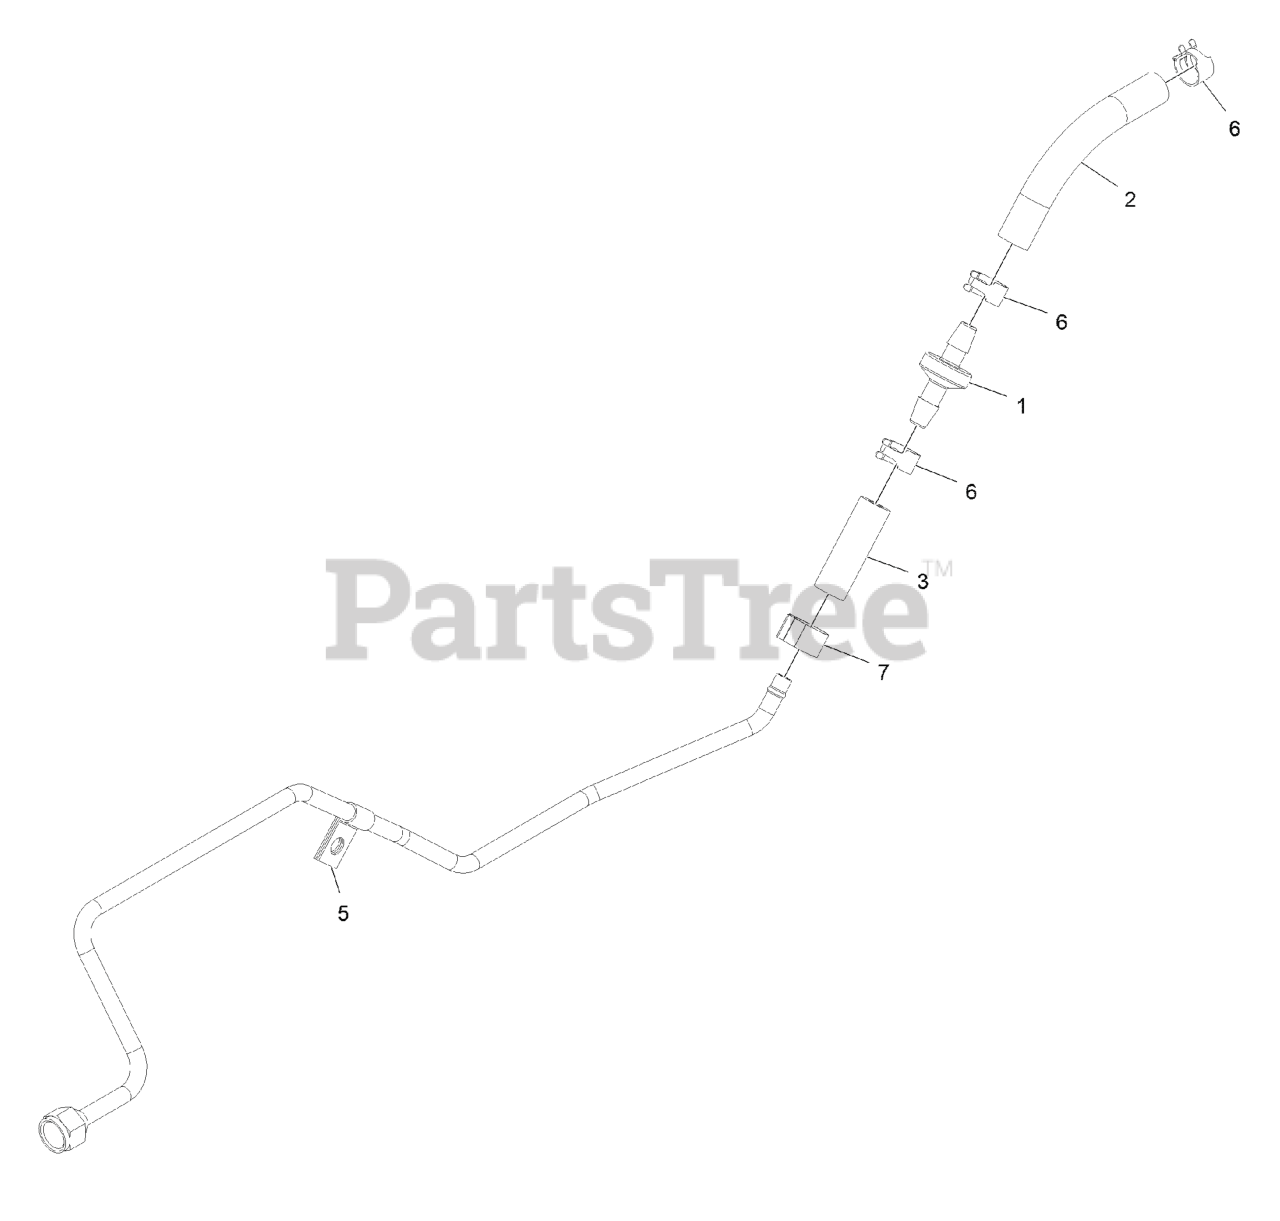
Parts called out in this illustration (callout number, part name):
1	VALVE-CHECK, FUEL
2	HOSE-FUEL
3	Hose-Fuel
5	CLIP-CLOSED, INSULATED
6	CLAMP-HOSE
7	Clamp-Hose, Fuel
